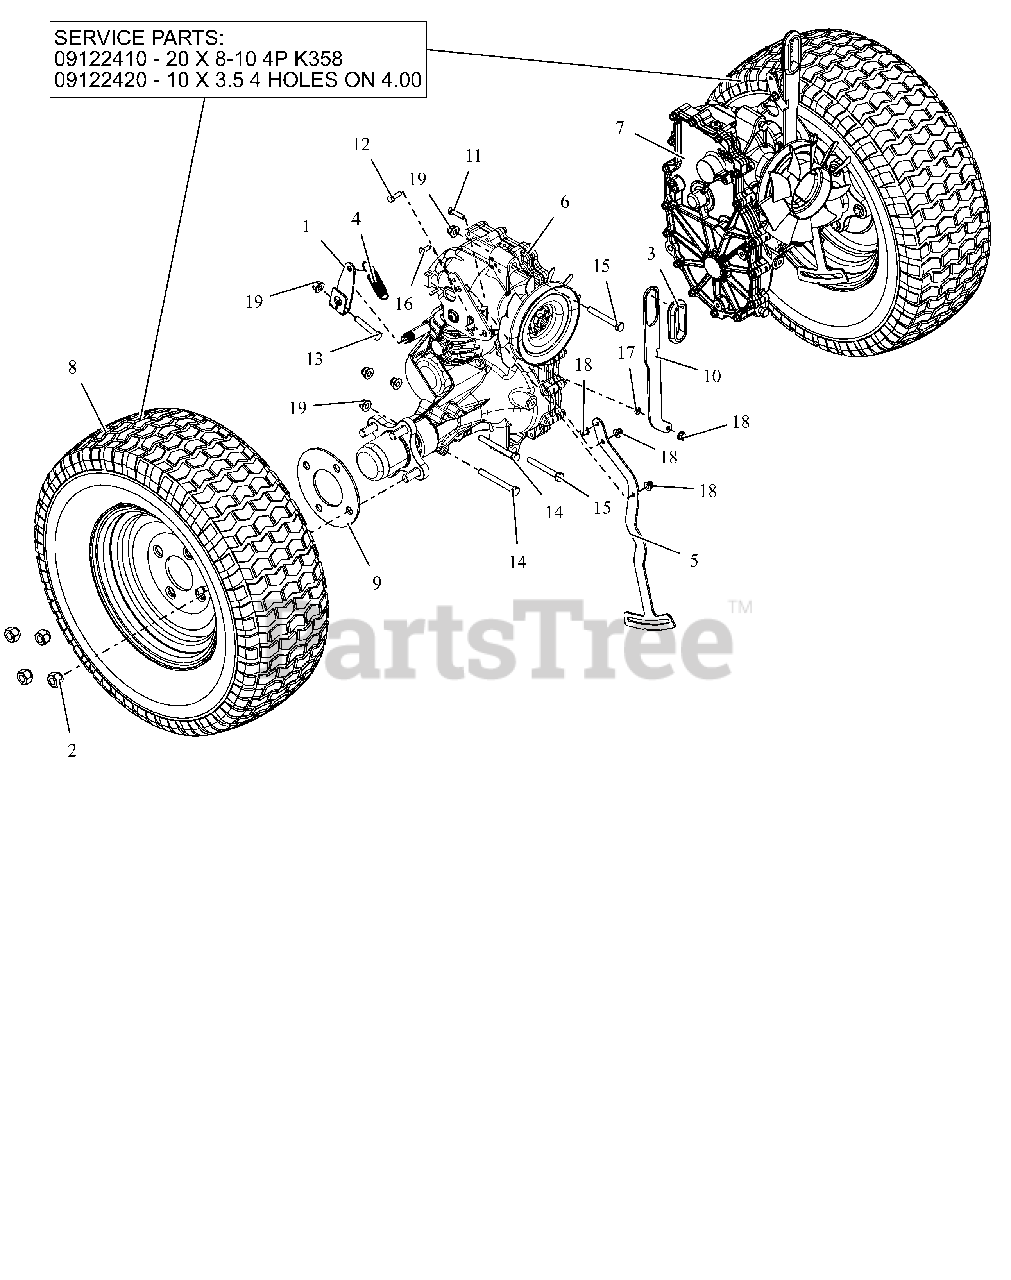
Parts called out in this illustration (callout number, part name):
1	WLDMT, LEVER BRAKE
2	NUT, WHEEL .50-20 ZCC
3	GROMMET 1.70ID X 2.0OD
4	SPRG, EXT .653 X .063 X 2.755
5	LEVER, TRANSAXLE
6	TRANSAXLE, HG ZT2800 RTS
7	TRANSAXLE, HG ZT2800 LTS
8	ASM, WHEEL & TIRE 20X8-10 K358
8	TIRE 20X8.00-10 4P K358
8	WHEEL, 10X3.5 4 HOLE ON 4"
9	SPACER, WHEEL 4-BOLT
10	LEVER, TRANS BYPASS SS
11	BLT, HEX M6-1.0 X 25 G8.8 ZCC
12	BLT, HEX M6-1.0 X 20 G8.8 ZCC
13	BLT, HEX M8-1.25 X 45 G8.8 ZCC
14	BLT, HEX M8-1.25X75 G8.8 ZCC
15	BLT, HEX M8-1.25 X 65 G8.8 ZCC
16	SCR,FLCSKH,M6-1.0X16 8.8ZC120
17	NUT, HEX-JAM M6-1.0 G8.8 ZCC
18	NUT,NYL-FLG M6-1.0 G8.8 ZCC
19	NUT,NYL-FLG M8-1.25 G8.8 ZCC
